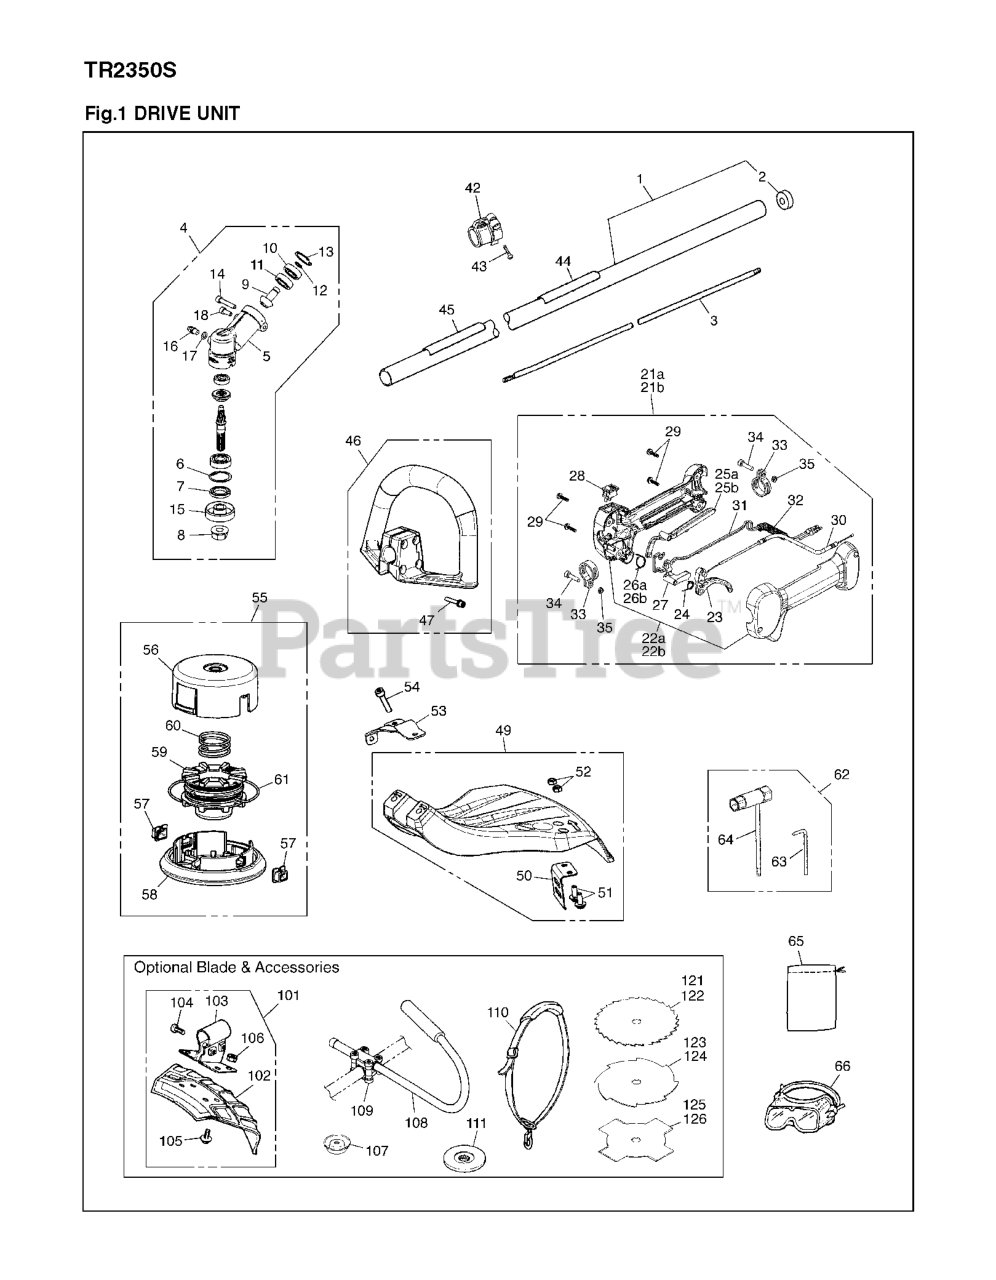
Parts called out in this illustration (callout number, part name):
1	PIPE COMP
4	GEARCASE
5	GEARCASE
6	RING,SNAP M26x1.2 RP-318013340
11	BALL BEARING
14	BOLT TORX
15	HOLDER(A)
18	BOLT, TORX
21	GRIP ASSY
22	GRIP HALF SET
23	LEVER, THROTTLE
24	SPRING, THROTTLE
25	LEVER FOR GRIP (RPLS -0600)
25	LEVER, SAFETY
26	SPRING JOINT
26	SPRING
27	LEVER JOINT
31	CORD - C
35	NUT
42	HANGER COMP.
44	DECAL
45	LABEL CAUTON FOR BC
46	HANDLE ASSY. (RPLS T319514001)
49	RP_GUARD ASSY
54	BOLT, TORX
55	4" TAP TRIMMER HEAD PT104
56	CASE (RPL T318915112)
58	COVER (RPLS T318915131)
59	HOLDER, CORD (RPLS T318915141)
61	CORD
62	TOOL SET
66	GOGGLExxx (RPLS
101	GUARD ASSY (RPLS 3554-1)
107	COVER (10MM)
108	HANDLE(L)
109	BRACKET A
110	STRAP ASSY
111	HOLDER (B)
121	Brushcutter Blade, 22 Tooth 9"
122	Brushcutter Blade, 24 Tooth 9"
123	BLADE, 8
124	Brushcutter Blade, 8 Tooth 9"
125	BLADE, 8
126	Brushcutter Blade, 4 Tooth 9"
